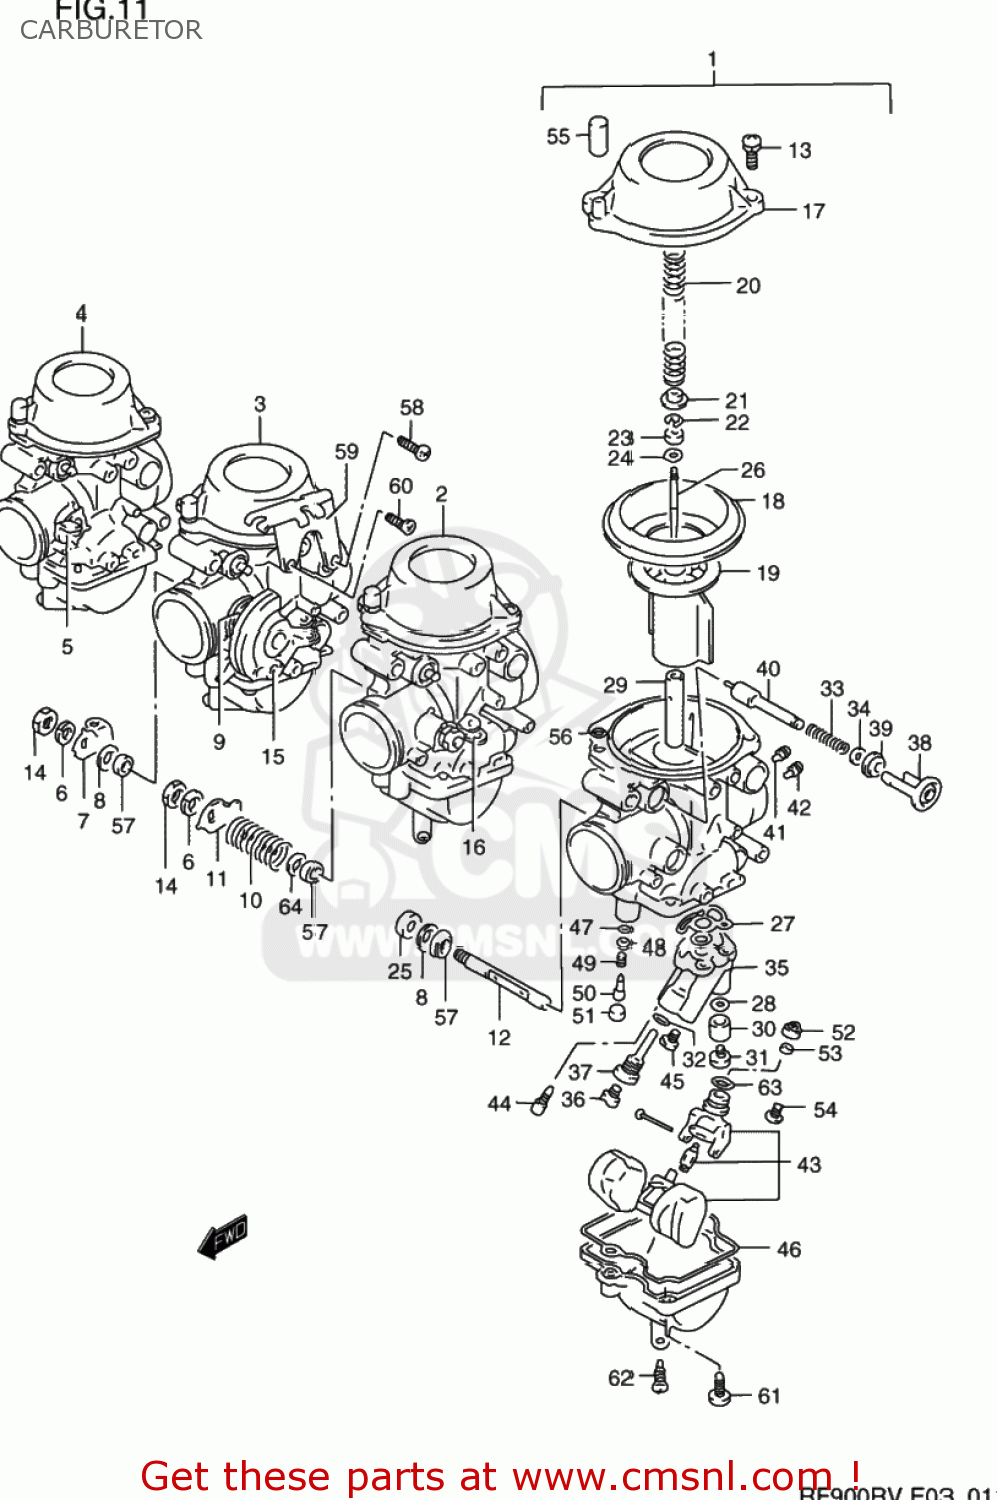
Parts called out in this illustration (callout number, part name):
1	CARBURETOR ASSEMBLY
2	CARBURETOR ASSEMBLY
3	CARBURETOR ASSEMBLY
4	CARBURETOR ASSEMBLY
5	SHAFT,THROTTLE
6	WASHER
7	LEVER,THROTTLE
8	GASKET,THROTTLE SHAFT (NAS)
9	SPRING
10	SPRING
11	SHAFT,THROTTLE
12	SHAFT,THROTTLE
13	SCREW
14	NUT
15	SHAFT,THROTTLE
16	LEVER,THROTTLE
17	COVER,DIAPHRAGM
18	DIAPHRAGM
19	VALVE,PISTON
20	SPRING
21	RING
22	E RING
23	RING
24	WASHER
25	RING
26	NEEDLE,JET(5DV3-1)
27	O RING
28	GASKET (NAS)
29	JET,NEEDLE(O-9)
30	RING
31	SCREW
32	O RING
33	SPRING
34	WASHER
35	JET BLOCK ASSEMBLY
36	JET
37	HOLDER,JET
38	HOLDER,GUIDE
39	CAP,STARTER
40	PLUNGER ASSY
41	JET,MAIN AIR(0.9)
42	JET,AIR (130)
43	FLOAT/NEEDLE VALVE ASSEMBLY
44	JET,PILOT(12.5)
45	JET,STARTER (52.5)
46	SEAL
47	O RING,PILOT AIR SCREW
48	WASHER
49	SPRING
50	SCREW,PILOT
51	PLUG
52	FILTER
53	RING
54	SCREW
55	CAP
56	O RING
57	SEAL
58	SCREW(5X14)
59	BRACKET
60	SCREW
61	SCREW
62	SCREW,DRAIN
63	O-RING,NEEDLE VALVE
64	RING
